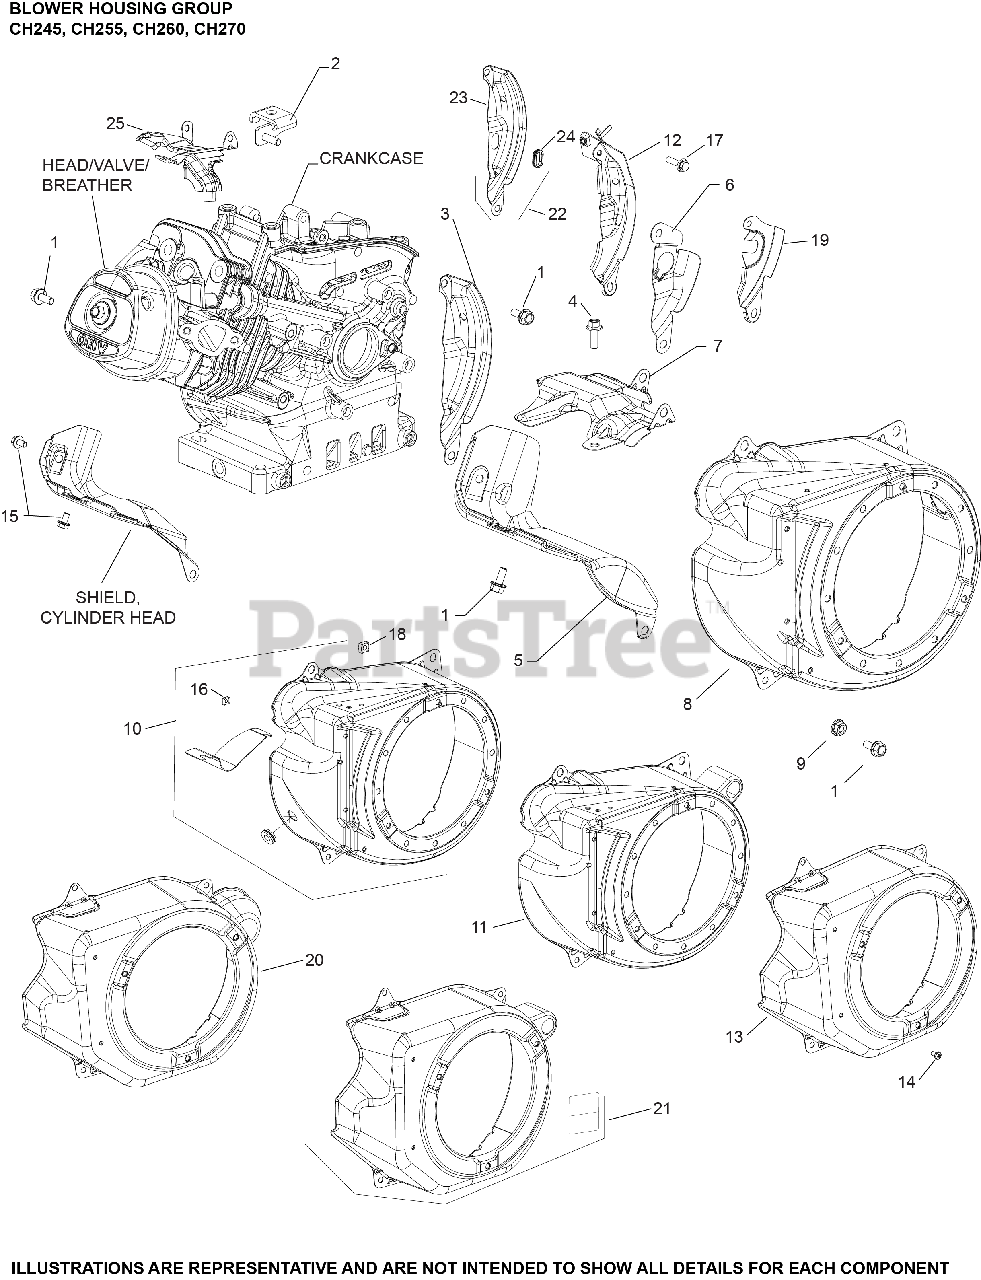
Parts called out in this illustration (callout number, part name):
1	SCREW, HEX FLANGE (M6)-USE 25 086 433-S
9	NUT, HEX FLANGE (M6) - USE 14 100 16-S
12	COVER, HOUSING LOWER BLOWER ASSEM
13	KIT, BLOWER HOUSING
14	SCREW, COVER TO BLOWER HOUSING
15	SCREW, HEX FLANGE (M6) (CKY)
17	SCREW, M6 X 22
